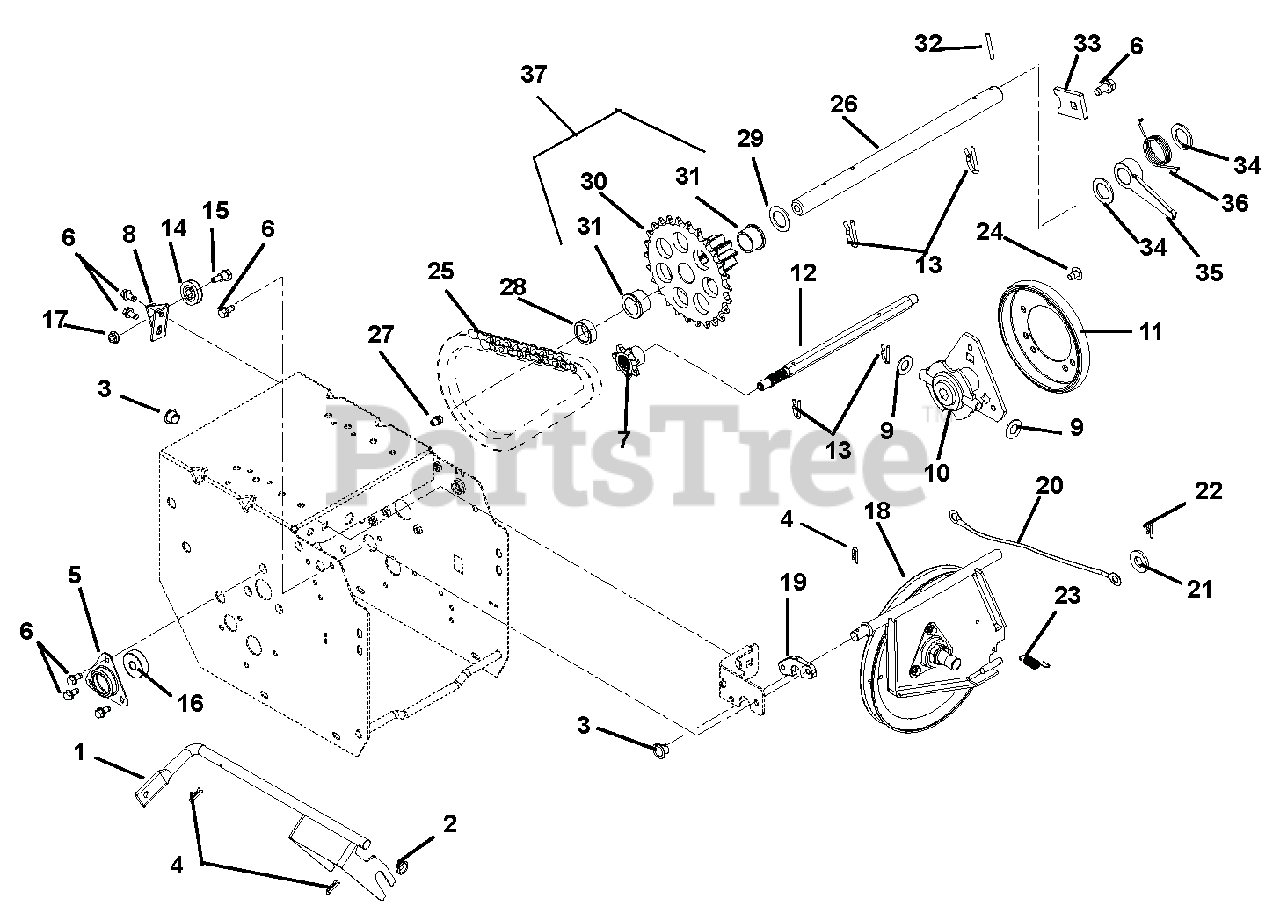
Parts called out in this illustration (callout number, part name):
1	WELDMENT, SHIFT FORK
2	BUSHING, POLYLINER-.50 SNAPIN
3	BUSHING, POLYLINER-.50 SPLIT
4	CLIP, SPRING
5	FLANGE, BEARING
6	SCR-TAP .25-20X.50 HWH TR YWZ
7	SPROCKET, PINION 7T W/SPLINE
8	BRACKET, CABLE PULLEY
9	WSHR-FL-STL .505X1.00X.062YWZC
10	CARRIER, DRIVE DISK
11	FRICTION, DISC
12	SHAFT, HEX W/SPLINE
13	PIN, SPRING CLIP
14	PULLEY, CABLE
15	BOLT, SHLDR-.375X.375X.25-20
16	BRG-BALL .437X1.375X.437
17	@NUT-LK-TOP-FLG .25-20 YWZC
18	PLATE, SWING - ASSEMBLY
19	SPACER, SWING GATE
20	CABLE, TRACTION - TRACTOR
21	@WSHR-FL-STL.344X.688X.065YWZC
22	PIN-HAIR INT .08X.18X1.18 YWZC
23	SPRING, EXT. .043X.438X1.64
24	SCR-TAP SERRDHDTX .31-18X.50BP
25	CHAIN - #41, 32 PITCHES
26	SHAFT, PINION
27	ZERK,FITTING .25X.125 DRIVE IN
28	BSHG-SLV, .635X.880X.305
29	WSHR-FL-STL .630X1.005X.062 YZ
30	PINION & SPROCKET
31	BSHG-FLG .625X.750X.500X.875
32	PIN-ROLL .125X1.00
33	TAB, ANTI ROTATION
34	WSHR-FL-STL .630X1.005X.062 YZ
35	LEVER, LOCK ARM
36	SPRING, TORSION
37	PINION & SPROCKET W/BUSHINGS
